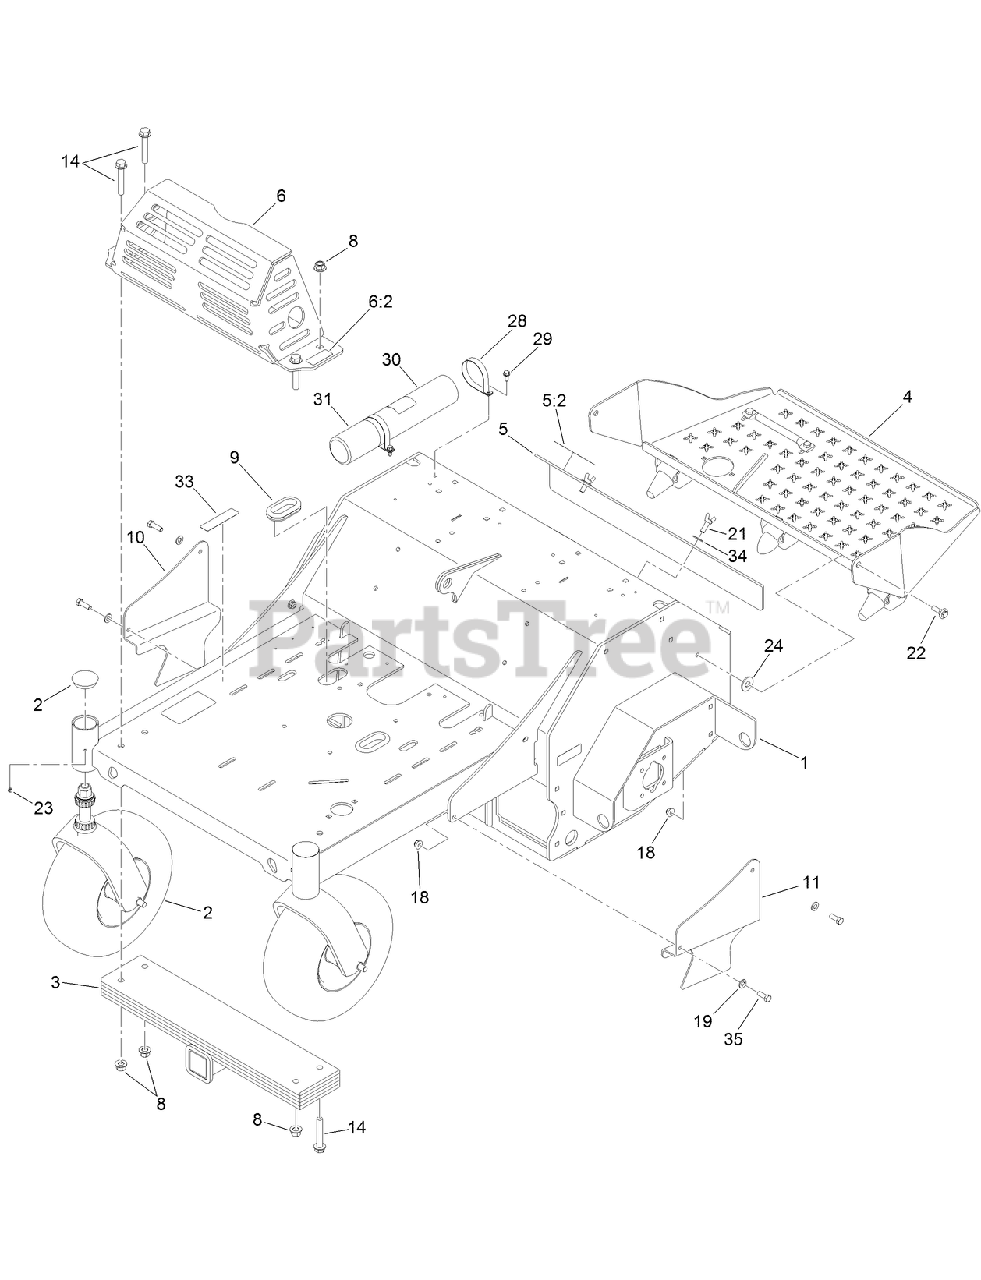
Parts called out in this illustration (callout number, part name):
1	MAIN FRAME ASM
2	FRONT CASTER ASM
4	PLATFORM W/ROCKER ASM
5	ACCESS COVER ASM
5:2	DECAL-OPERATION, TINE GROUND (CE)
6	MUFFLER GUARD ASM
6:2	DECAL-SURFACE, HOT
8	NUT-LOCK
9	GROMMET
10	GUARD-CHAIN, RH
11	GUARD-CHAIN, LH
14	SCREW-HF
18	NUT-HF, NI
19	WASHER-FLAT
21	SCREW-THUMB
22	SCREW-SHOULDER, HWH
24	WASHER-FLAT
28	R-Clamp
29	SCREW-HWH
30	TUBE-MANUAL
31	CAP-HOUSING
33	DECAL-ARRESTER, SPARK
34	WASHER-SPRING
35	SCREW-HH
